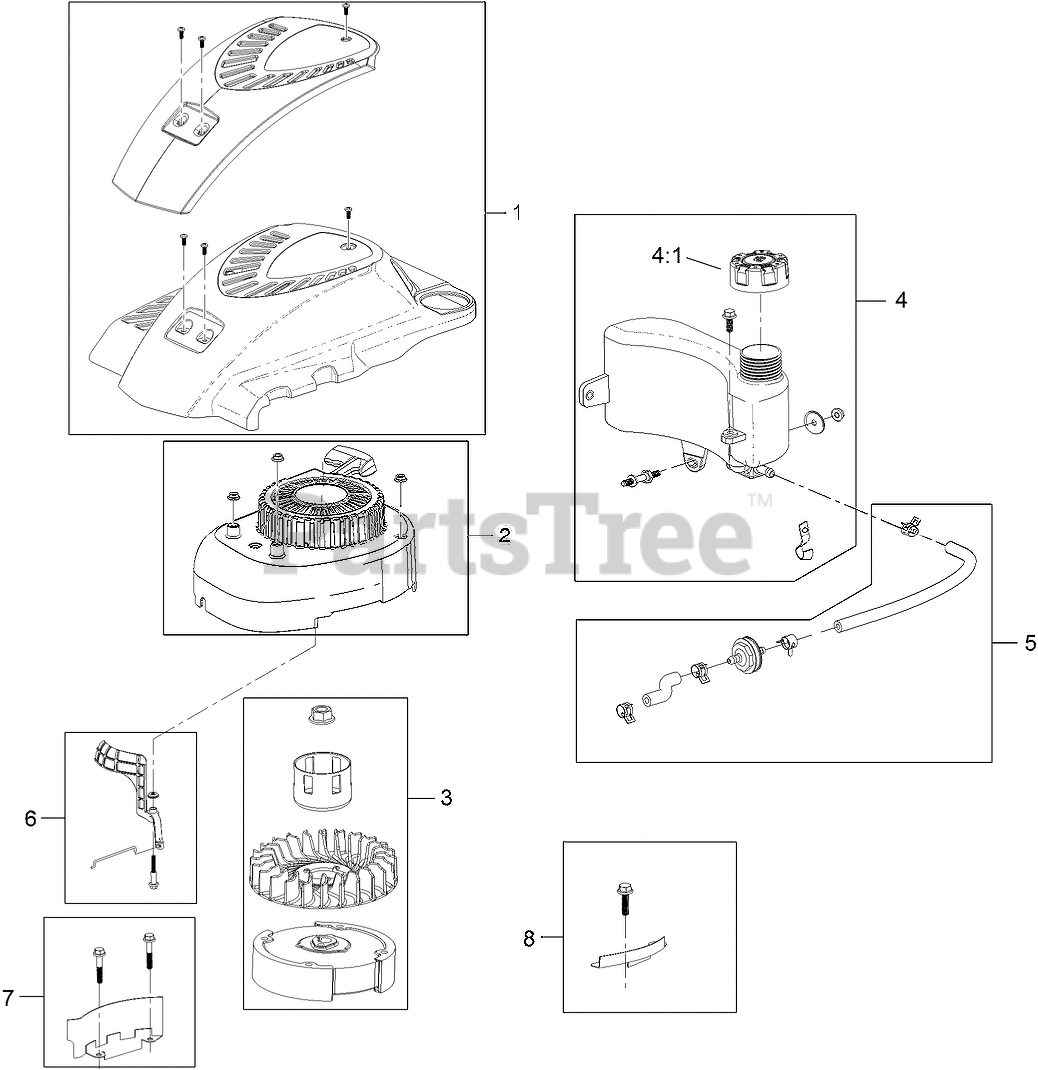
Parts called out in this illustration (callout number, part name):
1	Shroud ASM
2	SHROUD AND RECOIL ASM
3	FLYWHEEL AND FAN KIT
4	FUEL TANK KIT (CAP AND HARDWARE)
4:1	CAP-FUEL
5	FUEL LINE KIT
6	AIR VANE CHOKE KIT
7	FLYWHEEL SHIELD KIT
8	FLYWHEEL GUARD KIT
